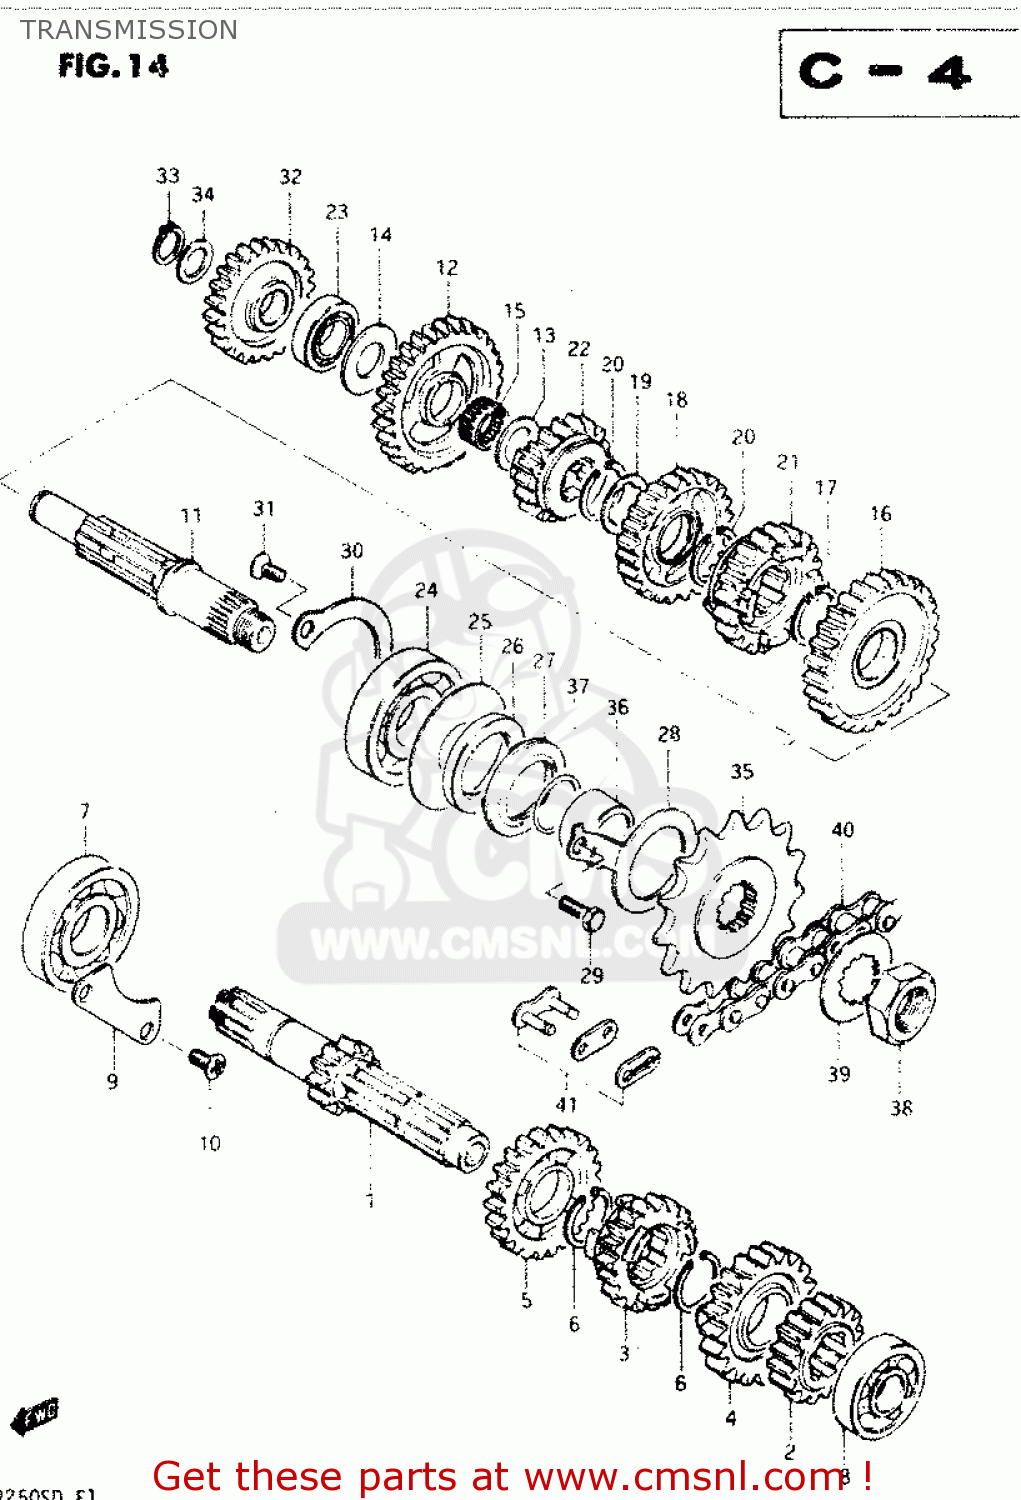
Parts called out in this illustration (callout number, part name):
1	SHAFT,COUNTER
2	GEAR,2ND DRIVE(NT:16)
3	GEAR,THIRD DRIVE (NT:19)
4	GEAR,FOURTH DRIVE
5	GEAR,FIFTH DRIVE
6	CIRCLIP
7	BEARING
8	BEARING
9	RETAINER,CNTR SHAFT BEARING
10	SCREW 6X12
11	SHAFT,DRIVE
12	GEAR,1ST DRIVEN(NT:29)
13	WASHER
14	WASHER
15	BEARING(17X21X9.8)
16	GEAR,2ND DRIVEN(NT:27)
17	CIRCLIP
18	GEAR,THIRD DRIVEN
19	WASHER,LOCK
20	CIRCLIP
21	GEAR,FOURTH DRIVEN
22	GEAR,FIFTH DRIVEN
23	BEARING(17X36X12)
24	BEARING(22X56X16)
25	WASHER(35X55X1)
26	OIL SEAL (30X43X5)
27	OIL SEAL (30X43X7)
28	RETAINER,DRIVE SHAFT OIL SEAL
29	BOLT
30	RETAINER,DRIVE SHAFT BEARING
31	SCREW
32	GEAR,KICK STARTER IDLE(NT:24)
33	CIRCLIP
34	WASHER
35	SPROCKET,ENGINE(NT:15)
36	SPACER,ENGINE SPROCKET
37	O RING(D:2.5,ID:21)
38	NUT
39	WASHER,LOCK
40	CHAIN ASSEMBLY,DRIVE
41	JOINT ASSEMBLY,CHAIN
